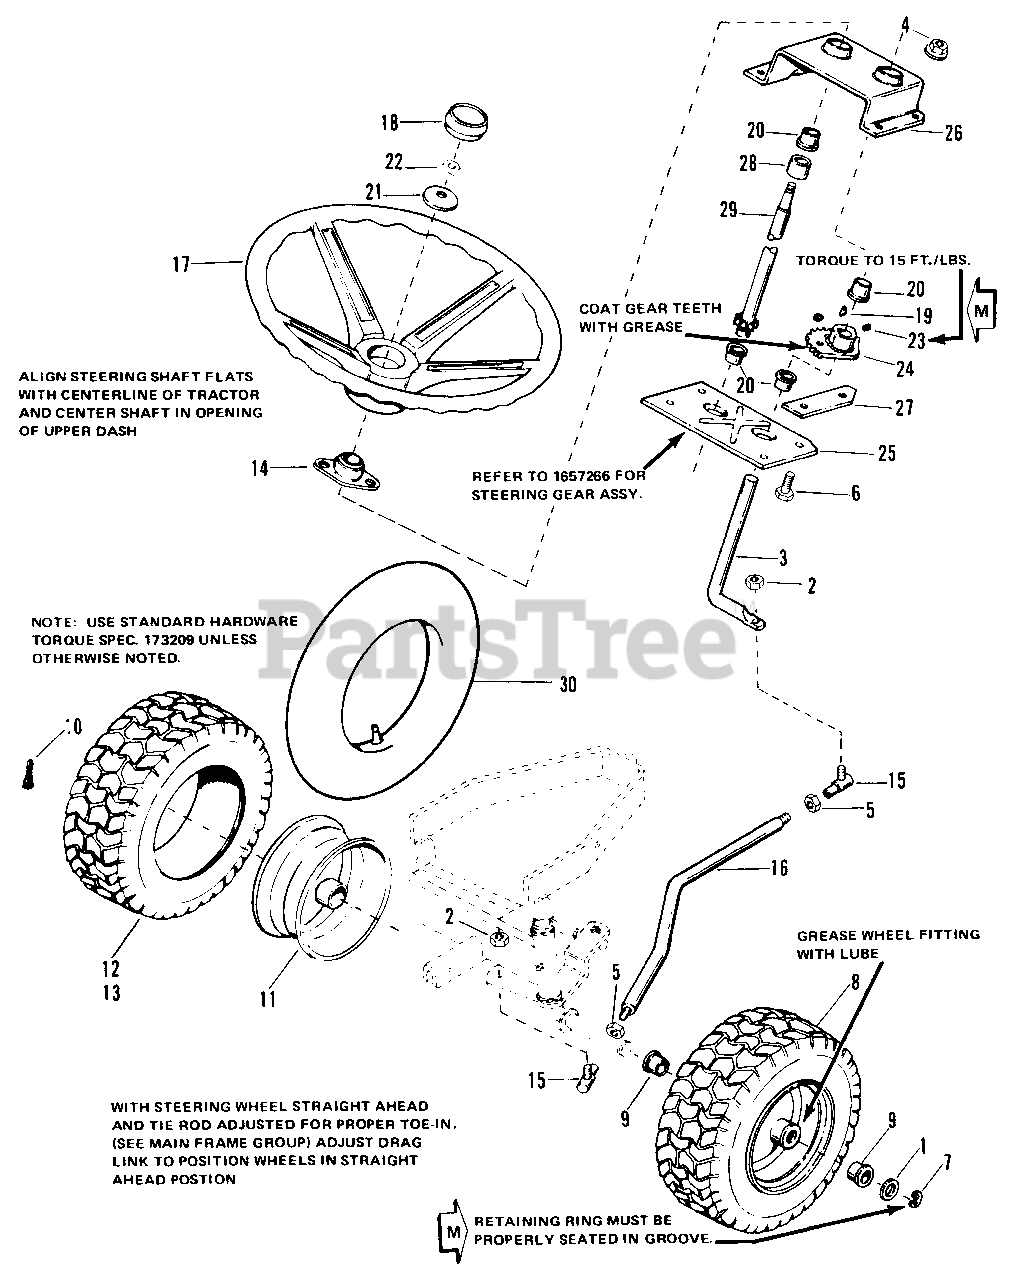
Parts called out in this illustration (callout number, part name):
2	LOCKNUT, Center, 3/8-24
3	ROD, Steering
4	NUT, Flange, Whiz, Lock, 5/16-18
5	NUT, Hex Jam, 3/8-24
6	CAPSCREW, Hex Hd. 5/16-18 x 1
7	RING, Retaining
8	WHEEL & TIRE ASSY., 15 x 6.00-6
9	BEARING, Relief
10	VALVE, Stem & Cap
11	WHEEL & BUSHING ASSY., 15-6
12	TIRE, 15 x 6.00-6, Carlisle
13	GOODYEAR TIRE, 15 x 6.00-6
15	BALL JOINT ASSY
16	DRAG LINK ASSY
17	WHEEL, Steering
18	CAP, Steering Wheel
21	WASHER, Compression
22	LOCKNUT, Hex, 5/16-18
23	SCREW, Set, Sq. Hd. Cup Pt., 5/16-18 x 5/8
24	GEAR, Steering
25	BASE PLATE, Steering
26	TOP PLATE, Steering
27	SPACER, Stop
29	SHAFT ASSY., Steering
30	TUBE, 15 x 6.00-6
